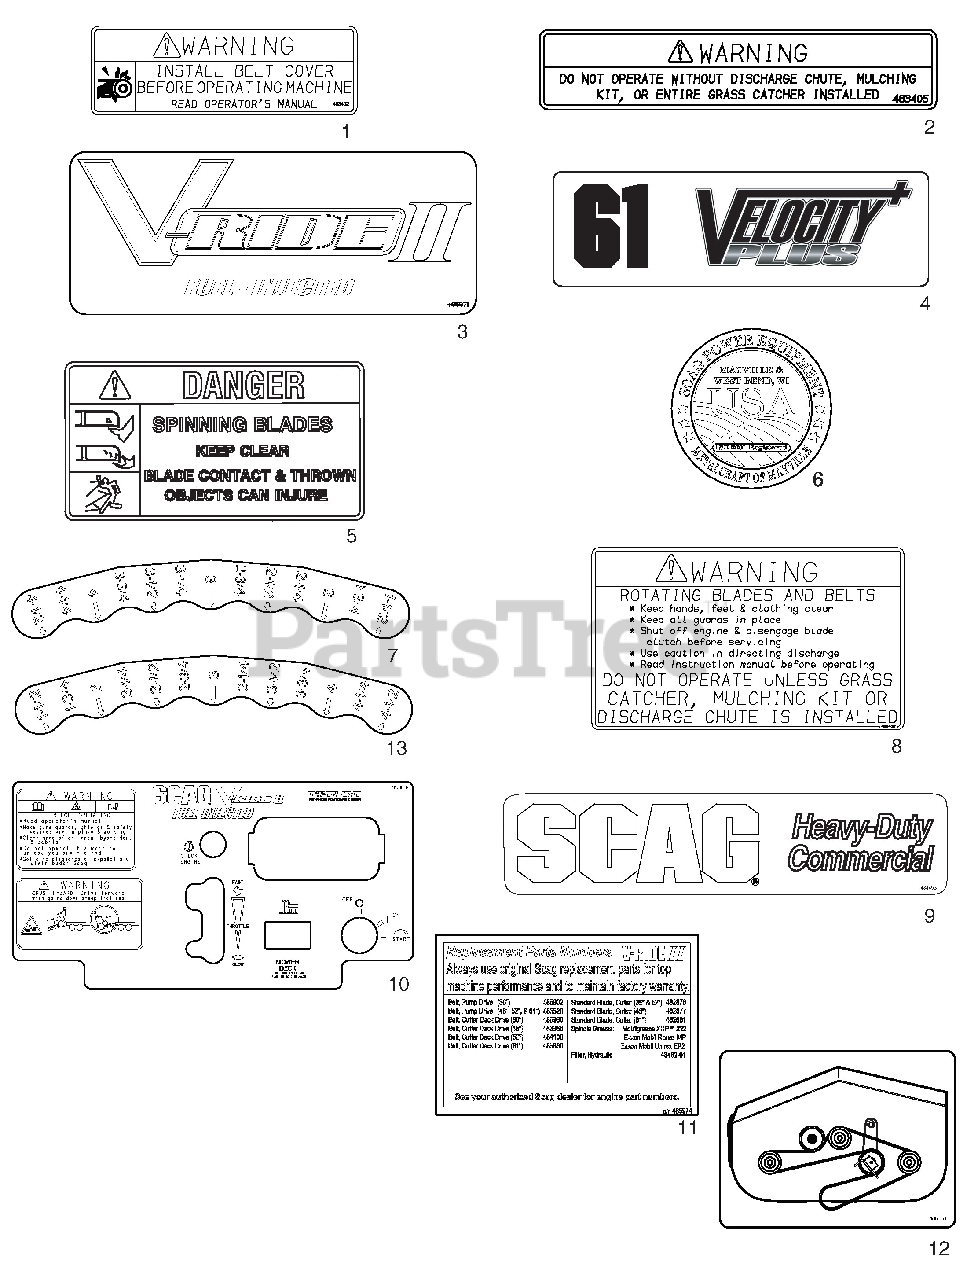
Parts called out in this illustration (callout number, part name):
1	Decal, Warning - Belt Cover
2	Decal, Warning
3	Decal, Belt Cover
3	Decal, Belt Cover - EFI
4	Decal, 36A
4	Decal, 48V
4	Decal, 52V
4	Decal, 61V
5	Decal, Spinning Blades
6	Decal, Metalcraft - USA
7	Decal, Deck Height - Outer
8	Decal, Warning - Knives
9	Decal, Scag Heavy Duty Commercial
10	Decal, Instrument Panel - SVRII36A
10	Decal, Instrument Panel - SVRII36A - Recoil Start
10	Decal, Instrument Panel - SVRII
10	Decal, Instrument Panel - SVRII-EFI
11	Decal, SVRII Replacement Parts
12	Decal, Belt Routing - SVRII36A
12	Decal, Belt Routing - SVRII48V, SVRII52V & SVRII61V
13	Decal, Deck Height - Inner
